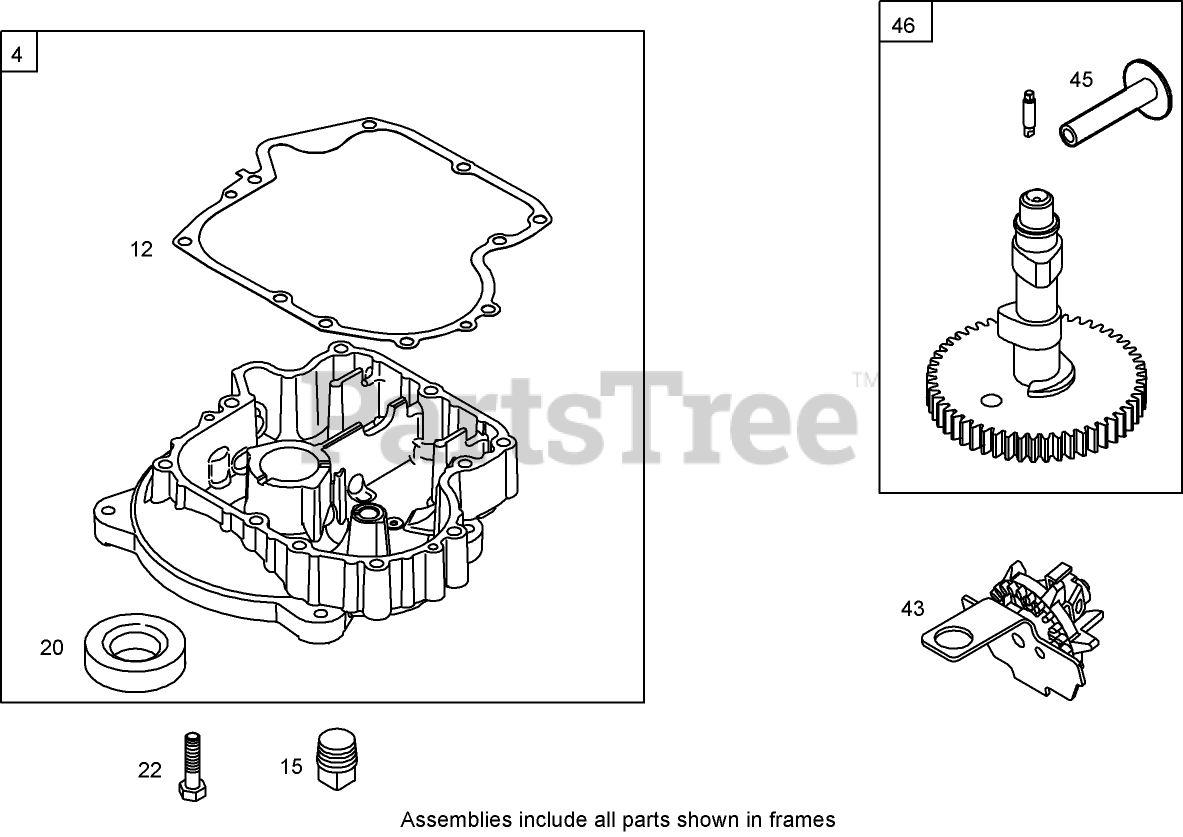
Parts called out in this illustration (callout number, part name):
4	Sump-Engine
12	Gasket-Crankcase
15	Plug-Drain, Oil
20	Seal-Oil (PTO Side)
22	Screw
43	Slinger-Governor, Oil
45	Tappet-Valve
46	Camshaft
